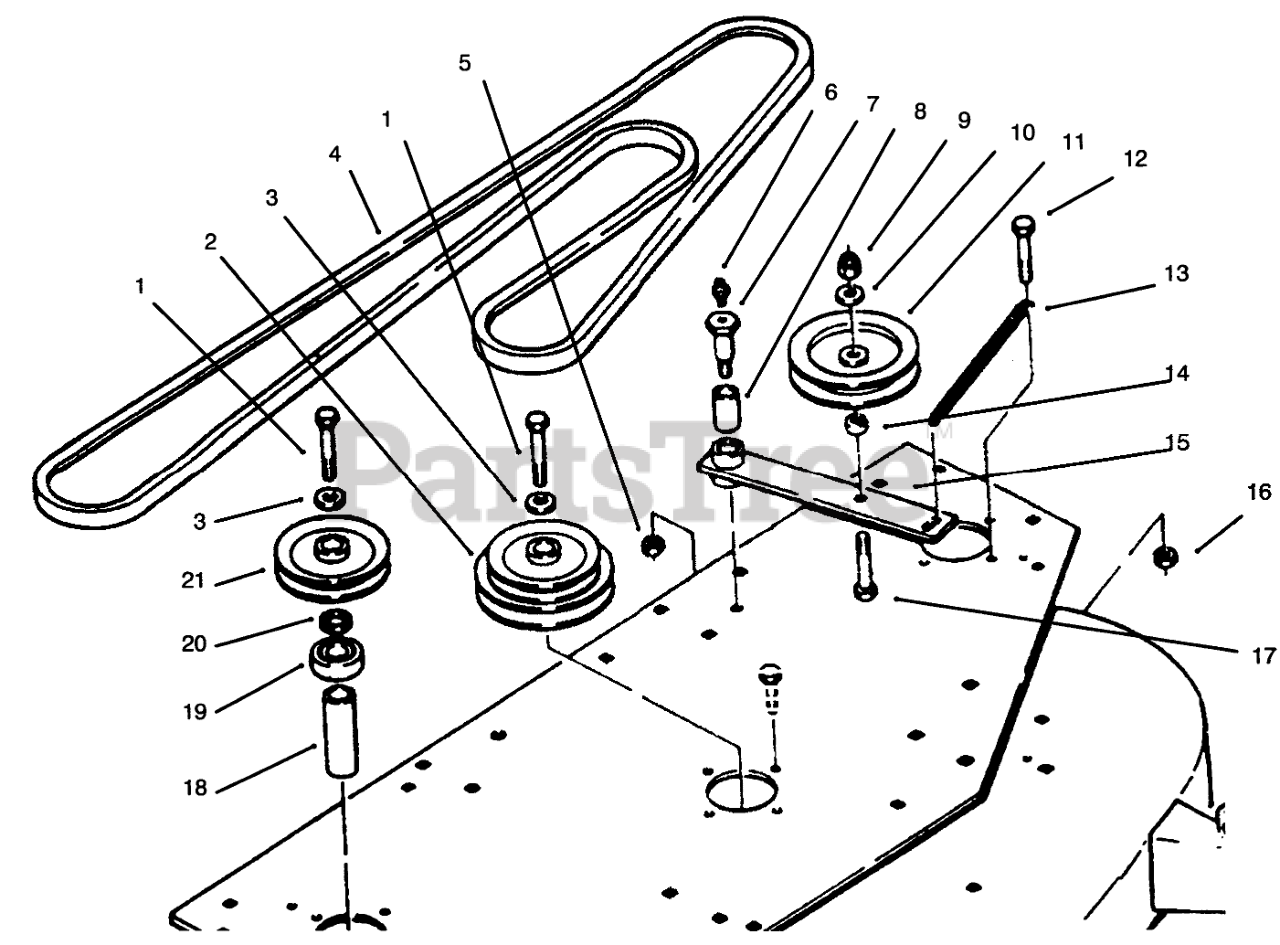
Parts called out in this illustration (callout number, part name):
1	Pulley-Center Spindle
3	WASHER-SPECIAL
4	BELT-V
5	NUT-LOCK, NI
6	FITTING-GREASE, 90 DEG
7	BOLT-SHOULDER
8	BUSHING
9	NUT-LOCK, NI
10	WASHER-FLAT
11	PULLEY-IDLER
12	SCREW-HH
13	SPRING-EXTENSION
14	SPACER
15	Idler Arm Assembly (Incl. Ref. #9)
16	NUT-JAM
17	SCREW-HH
18	Spacer
19	Spacer
20	Spacer
21	PULLEY-OUTER
